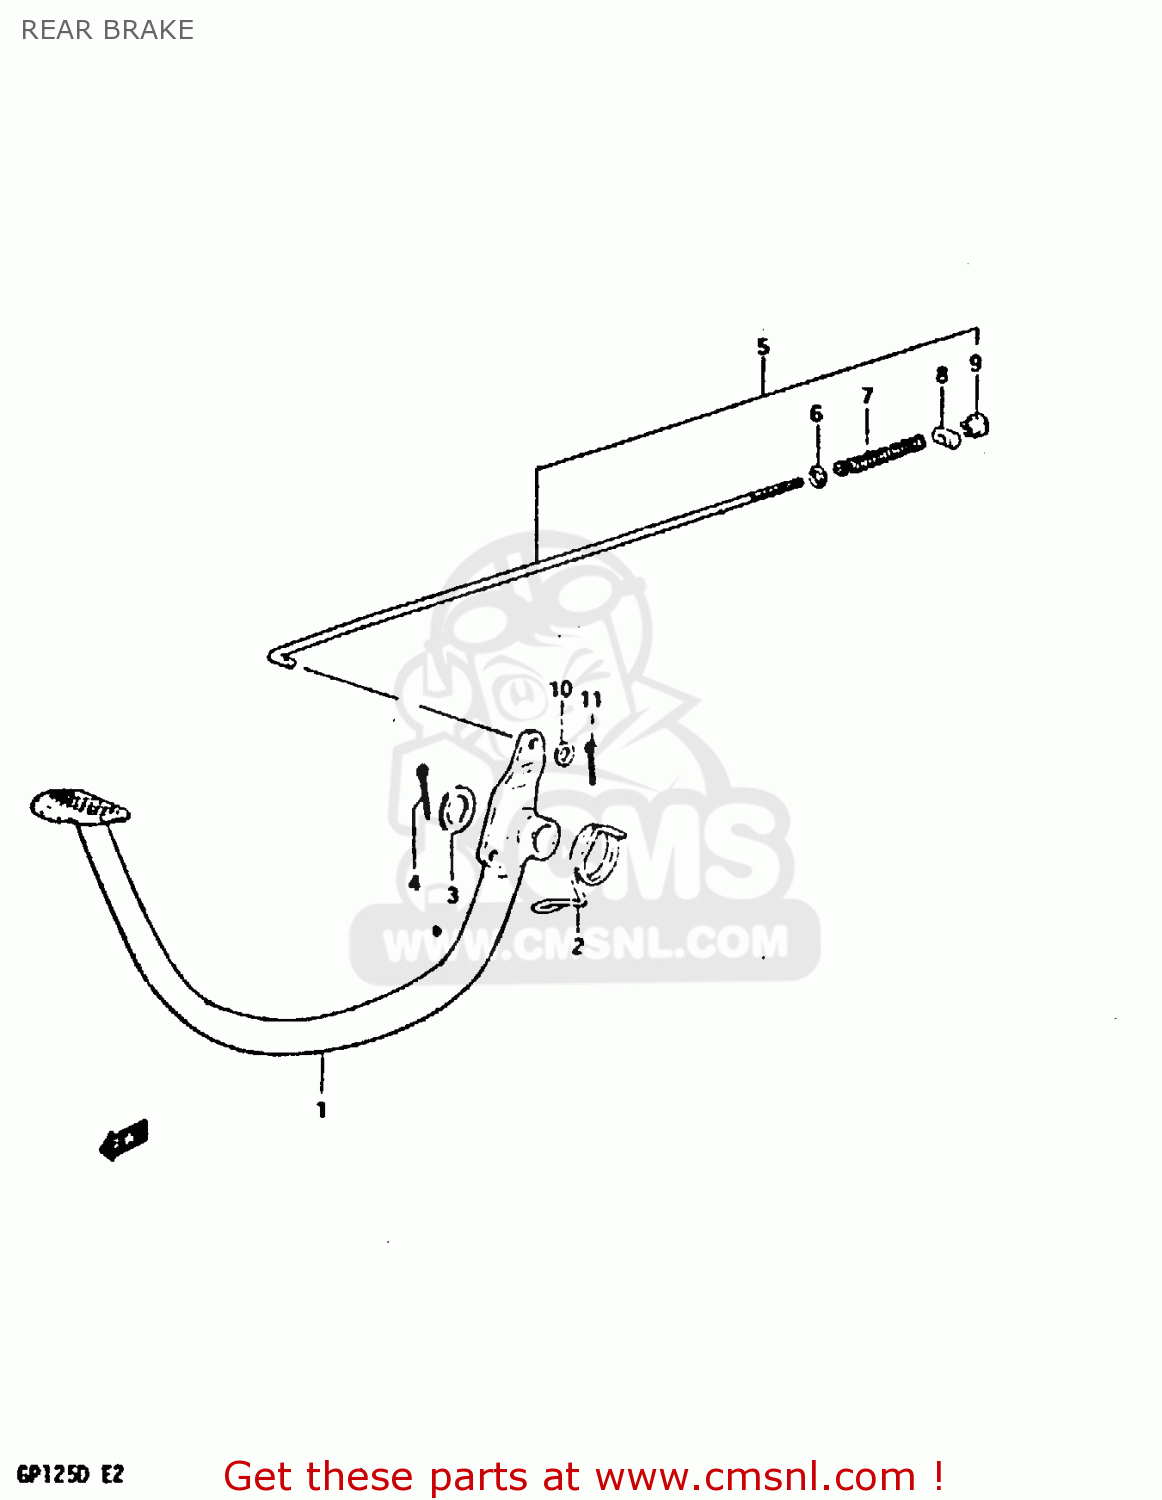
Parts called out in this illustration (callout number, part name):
1	PEDAL,BRAKE
2	SPRING
3	WASHER(15.5X26X2.3)
4	COTTER PIN
5	ROD ASSY, REAR BRAKE
6	WASHER
7	SPRING
8	PIN(11X18)
9	NUT
10	WASHER
11	PIN 20X20
